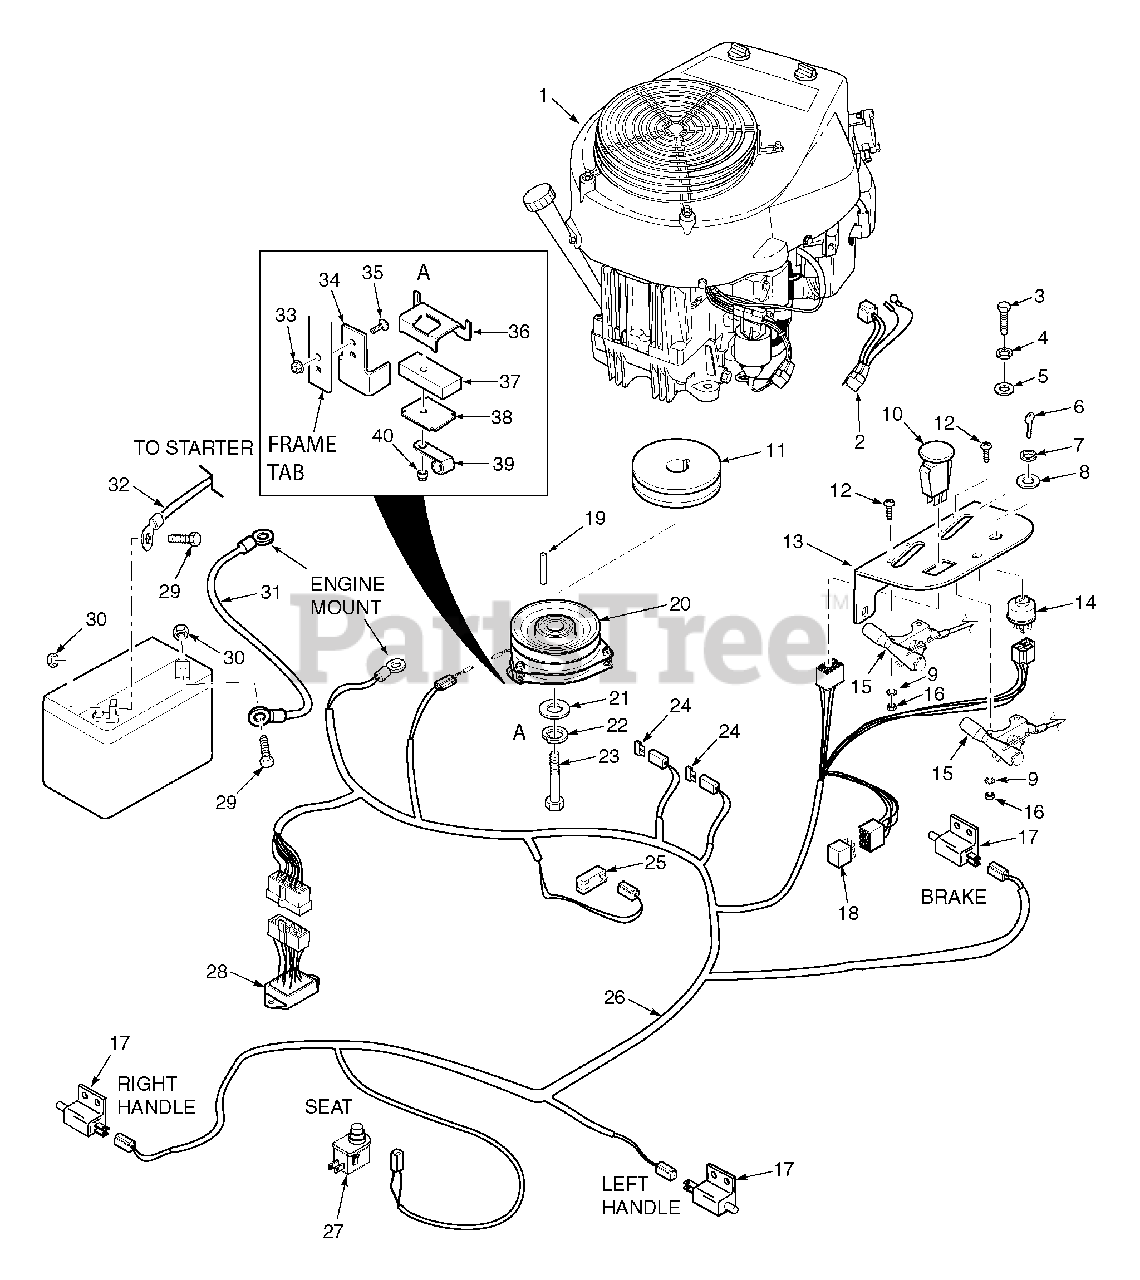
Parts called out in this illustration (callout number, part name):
1	Engine, Honda 16hp
2	Wire Harness Adapter, SZC Kawasaki
3	Bolt, Hex Head 5/16-18 x 3/4"
4	Lockwasher, 5/16
5	Flatwasher, 5/16-.375 x .875 x .083
6	Key, Ignition
7	Nut, Hex 5/8-32
8	Lockwasher, 5/8" Internal
9	Lock Washer, #10 External Tooth
10	Switch, PTO
11	Pulley, 5.45" Dia. 1" Bore
12	Screw, #10-32 x 3/4"
13	Instrument Panel
14	Switch, Ignition
15	Control Cable
16	Nut, Hex #10-32
17	Switch, N/O
18	Relay
19	Key, 1/4 x 1/4 x 3-1/4"
20	Clutch Assembly, GT2.5 - 1" Bore
21	Flatwasher, 7/16-.469 x 1.75 x .25
22	Lockwasher, 7/16 Spring
23	Bolt, Hex Head 7/16-20 x 2-1/2" w/Patch
24	Fuse, 20 amp
25	Hourmeter
26	Wire Harness, SZC
27	Switch, Seat
28	Electric Module
29	Bolt, Hex Head 1/4-20 x .5"
30	Nut, Hex 1/4-20
31	Battery Cable, Negative Black
32	Battery Cable, Positive Red
33	Nut, Elastic Stop 5/16-18
34	Plate, Clutch Anti-Rotation
35	Bolt, Carriage 5/16-18 x 1"
36	Retainer, Clutch
37	Rubber Pad, Clutch Stop
38	Plate, Backing
39	Clamp, Cable 1/2" ID
40	Nut, Elastic Stop 5/16-18
